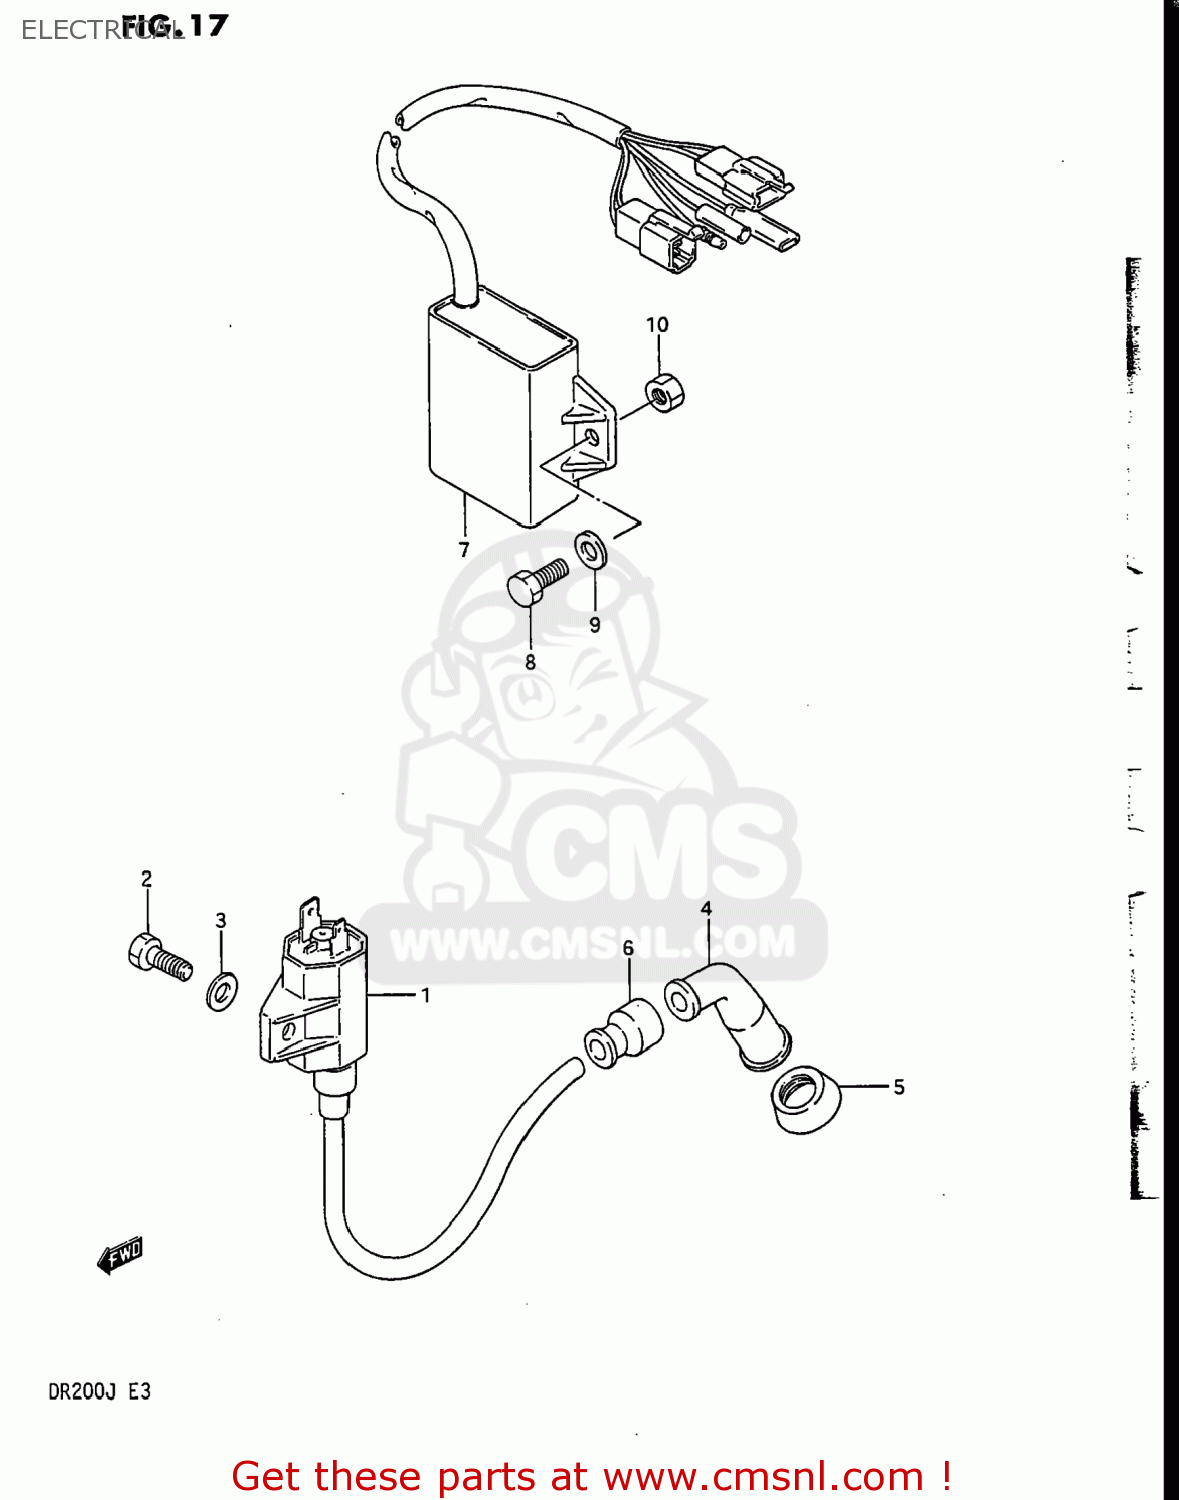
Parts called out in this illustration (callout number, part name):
1	COIL ASSEMBLY,IGNITION
2	BOLT
3	WASHER, LOWER
4	CAP,SPARK PLUG
5	SEAL,SPARK PLUG CAP
6	SEAL,SPARK PLU
7	CDI UNIT
8	BOLT
9	WASHER, LOWER
10	NUT
